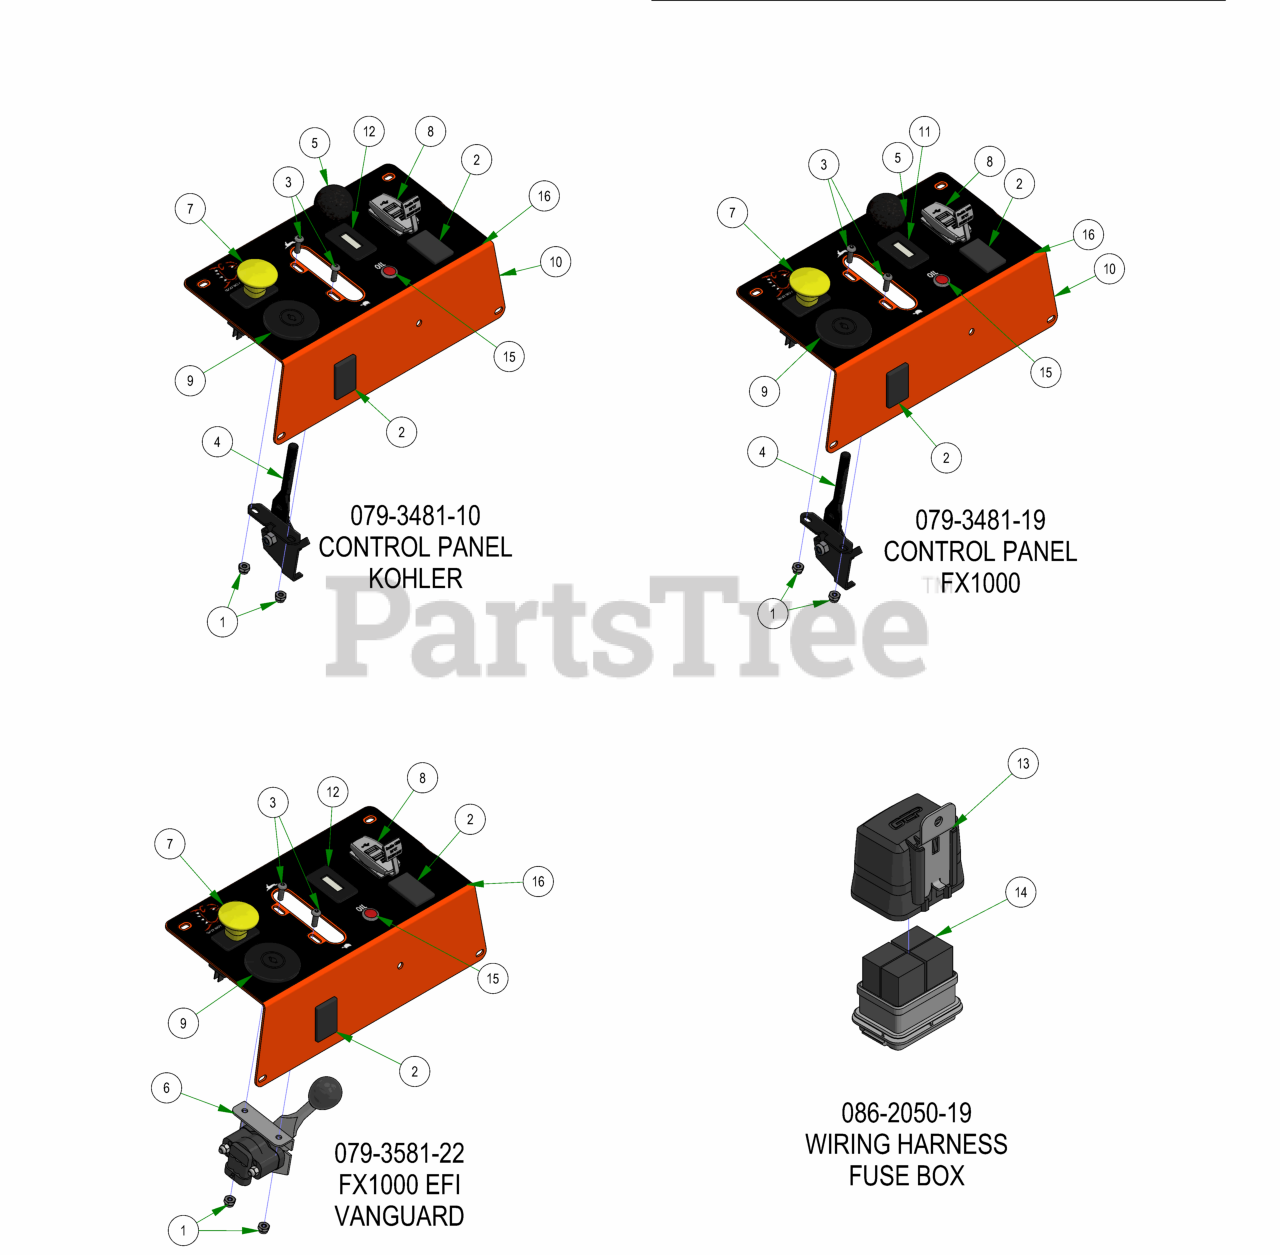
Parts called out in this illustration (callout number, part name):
1	10-24 NYLON INSERT LOCKNUT ZINC
2	Light Plug
3	10-24 X 5/8 BUTTON SOCKET CAP SCREW 18-8 STAINLESS STEEL
4	Universal Throttle Head - 2012
5	Throttle Knob
6	Kawasaki \ Kohler Drive By Wire
7	PTO Switch
9	Ignition Switch
10	2022 Rebel Control Panel
11	Tachometer
12	Tachometer
13	Relay Block Cover Replacement Kit
16	2022 Rebel/Rogue Control Panel Decal
